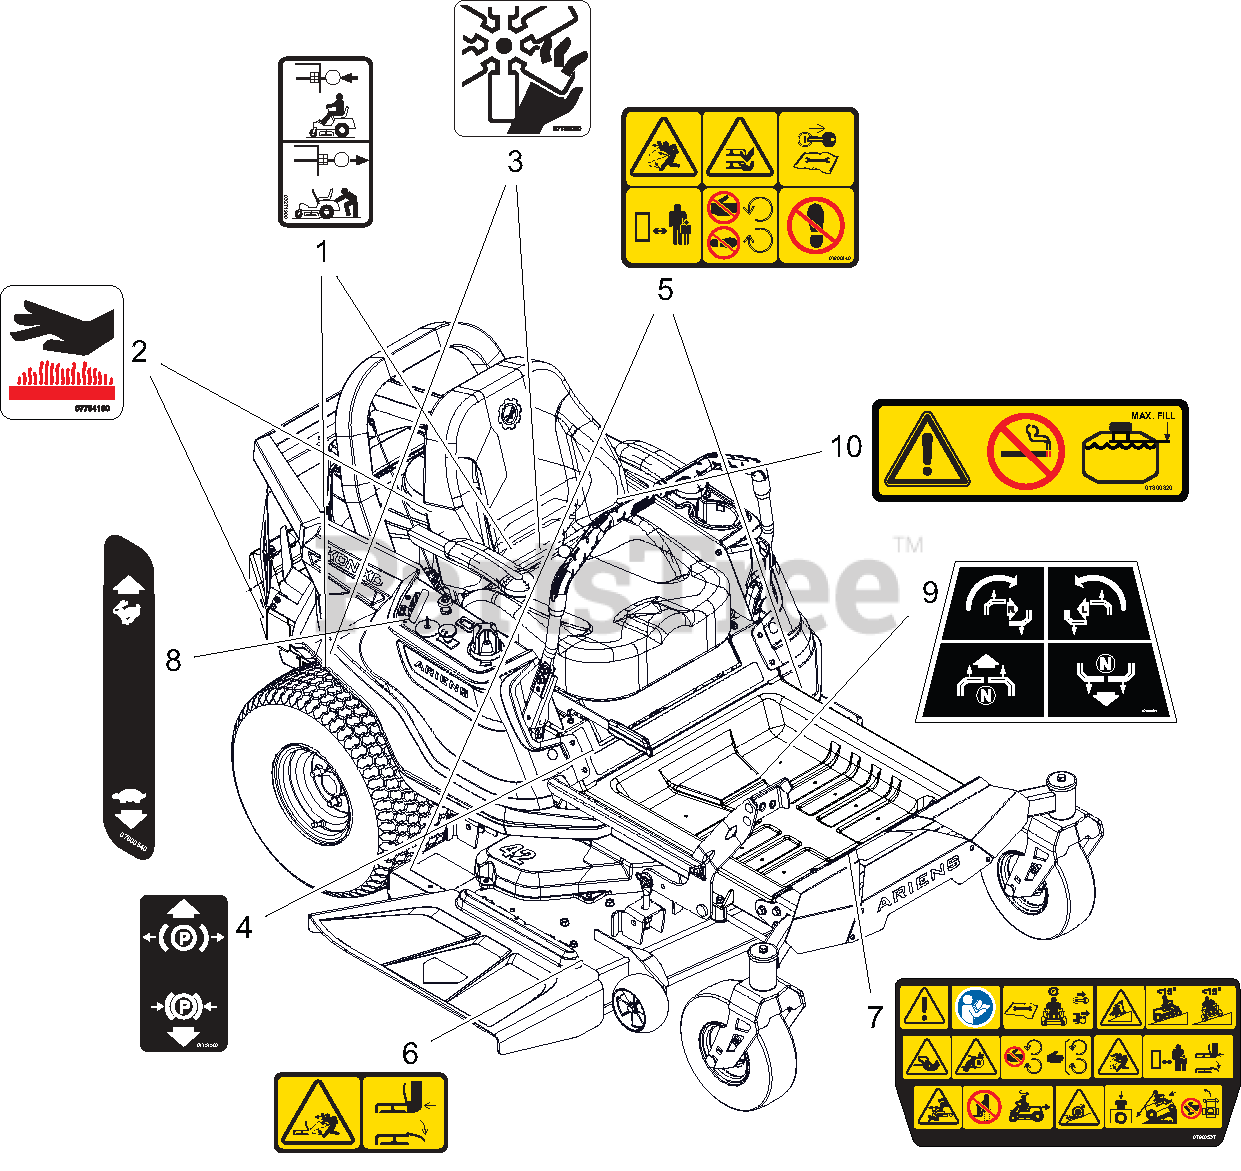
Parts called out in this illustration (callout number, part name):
1	DECAL, TRANSMISSION DISCONNECT
2	DECAL, HOT SURFACE
3	DECAL, DANGER FAN
4	DECAL, PARKING BRAKE LEVER
5	DECAL, SAFETY - MOWER DECK
6	DECAL, SAFETY - DECK GUARDING
7	DECAL, MAIN SAFETY
8	DECAL, DASH DECAL
9	DECAL, STEERING
10	DECAL, FUEL WARNING
